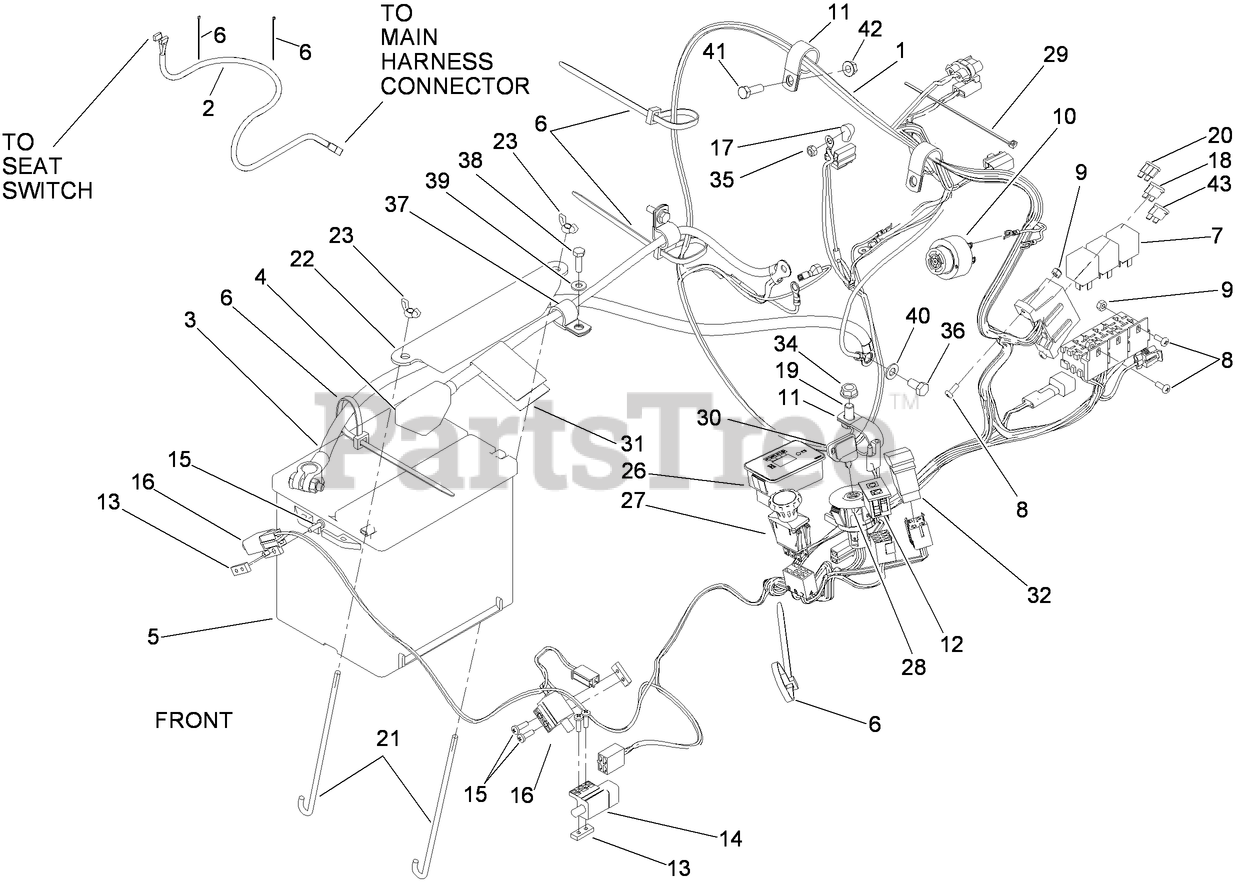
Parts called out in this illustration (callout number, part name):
1	HARNESS-WIRE
2	HARNESS-WIRING, SEAT
3	CABLE-BATTERY, NEGATIVE
4	CABLE-BATTERY, POSITIVE
5	BATTERY-DRY
6	TIE-PLASTIC
9	NUT-LOCK, NI
10	ALARM-TONE, DUAL
11	CLIP-LOOM
12	LAMP-WARNING
13	PLATE-TAPPED
14	SWITCH
15	SCREW-PPH
16	SWITCH-OPEN, NORMALLY
17	CAP-INSULATOR, RED
18	FUSE-40 AMP
19	SCREW-HH
20	FUSE-BLADE, 30 AMP
21	Bolt-Holddown
22	HOLDDOWN-BATTERY
23	WINGNUT
26	HOUR METER ASM
27	SWITCH-PTO, 10 AMP
28	SWITCH-IGNITION
29	TIE-CABLE
30	KEY-IGNITION
31	DECAL-INSTRUCTIONS, CHARGING
32	SWITCH-ROCKER
34	NUT-HHF, WHIZ
35	NUT-LOCK
36	SCREW-HH
37	CLIP-LOOM
38	SCREW-HH
39	WASHER-FLAT
40	WASHER-PLAIN
41	SCREW-HH
42	NUT-HF
43	FUSE-BLADE, 10 AMP
